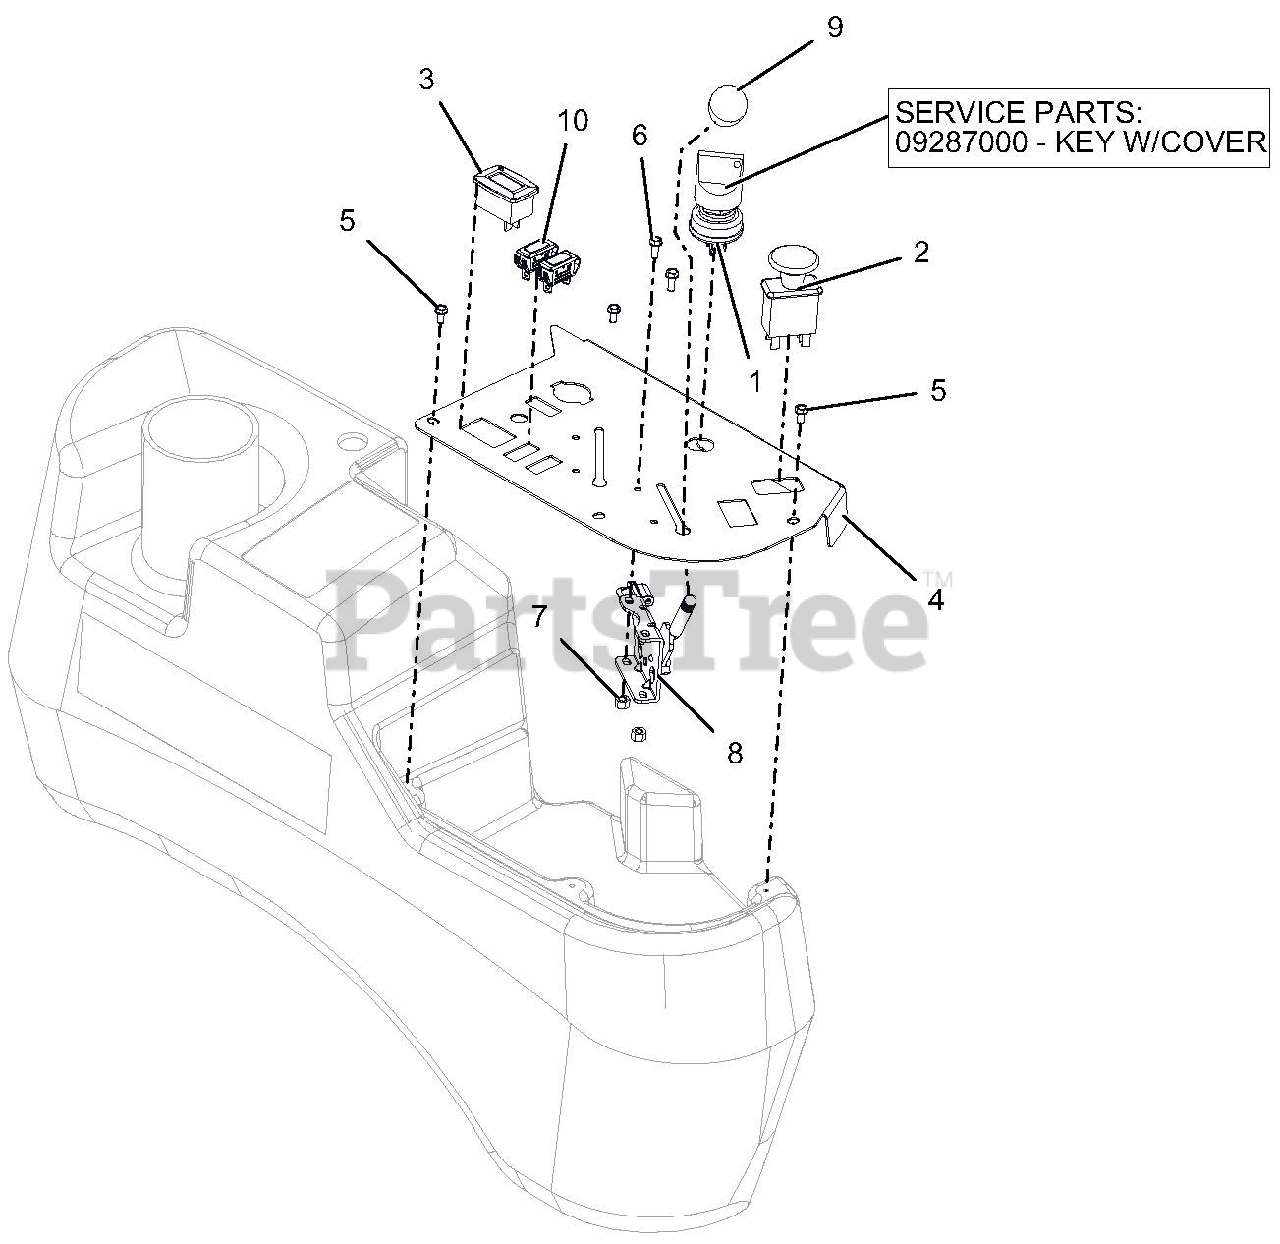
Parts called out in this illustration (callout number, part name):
1	SWITCH, IGNITION
1	KEY W/COVER
2	SWITCH, CLUTCH
3	METER, HOUR W/MAINTENANCE
4	PANEL, CONTROL
5	SCR-MCH 10-24X.38 HWHSTAINLESS
6	@SCR-MCH 10-24X.50 HWH YWZC
7	NUT-LK-NYL #10-24 YWZC
8	CABLE, PRO-CONTROL THROTTLE
9	KNOB, CONTROL BLACK .38-16X.50
10	LIGHT, INDICATOR
